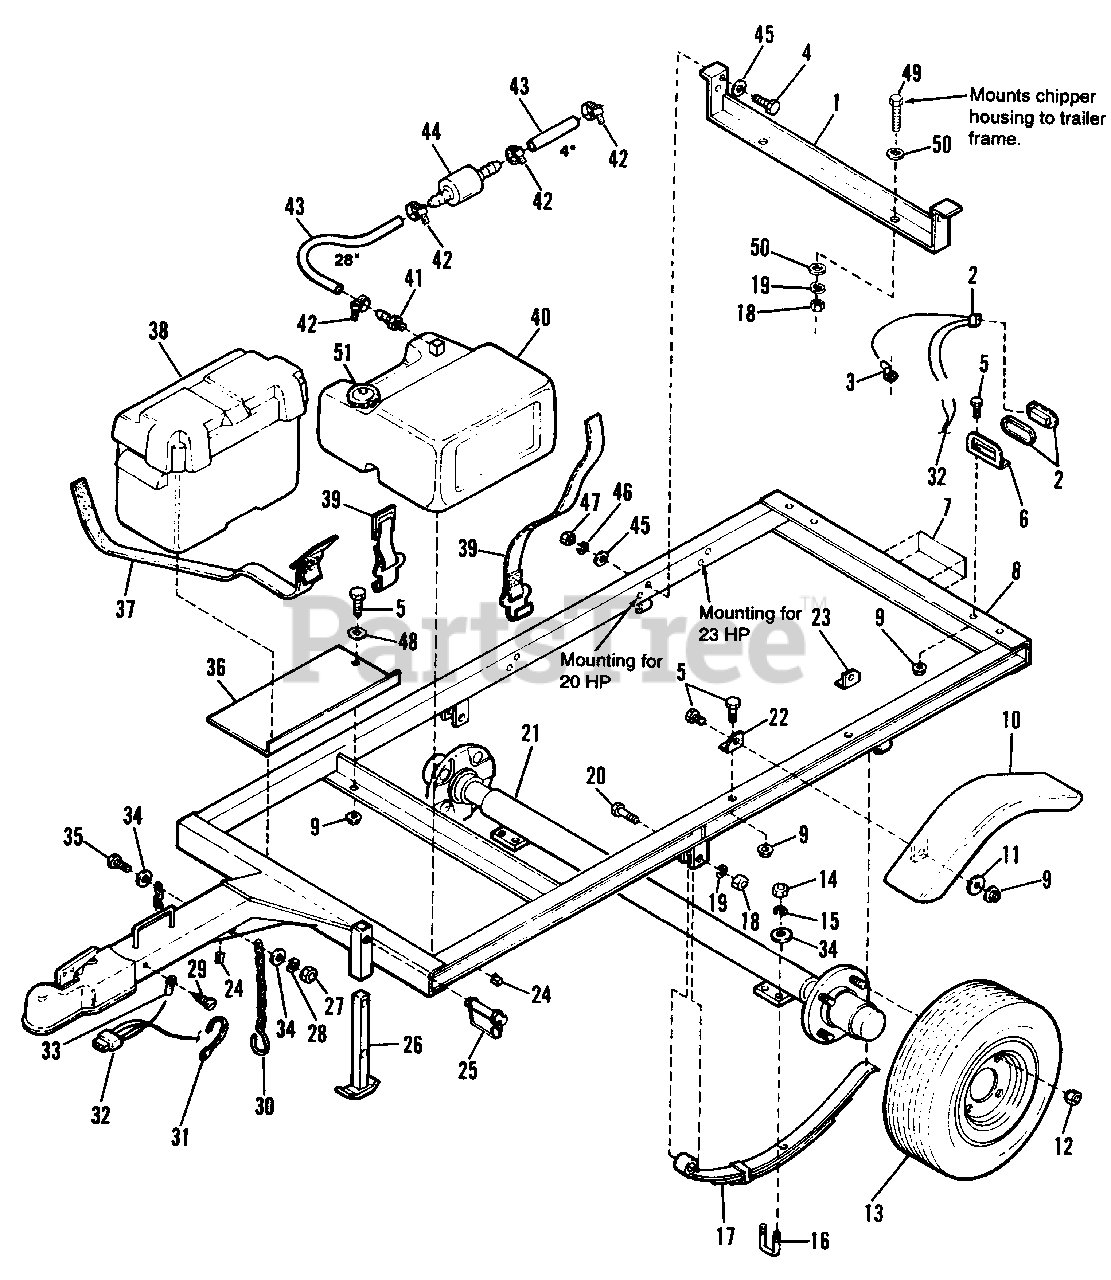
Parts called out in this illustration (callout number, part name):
1	BRACKET, Mounting, 20 HP
1	BRACKET, Mounting, 23 HP
2	TRUCK LIGHT
3	RING TONGUE, Vinyl
4	CAPSCREW, 7/16-14 x 1-1/4
5	CAPSCREW, Hex Hd., 5/16-18 x 3/4
6	BRACKET, Light Mounting
7	LOGO, Baker
8	TRAILER ASSEMBLY
9	NUT, Whiz Lock, 5/16-18
10	FENDER, Round
11	WASHER, Fender, 5/16 x 1-1/4 O.D.
13	WHEEL & TIRE ASSY., 5.70 x 8
14	NUT, 3/8 16
15	LOCKWASHER, 3/8
16	U-BOLT, 3/8-16
17	LEAF SPRING
18	NUT, Hex, 1/2-13
19	LOCKWASHER, 1/2
20	CAPSCREW, 1/2-13 x 3
21	AXLE ASSEMBLY
22	BRACKET, Fender Mounting, L.H.
23	BRACKET, Fender Mounting, R.H.
24	CLAMP, Cable
25	LOCK, Snap, 1/2 x 3-1/2
26	JACK ASSEMBLY
27	NUT, Hex, 3/8-16
28	LOCKWASHER, 3/8
29	SCREW, Sheet Metal
30	SAFETY CHAIN
31	TIE, Wore, 4"
32	HARNESS, Wiring, 117-1/2
33	TONGUE, Nylon Ring
34	WASHER, 3/8
35	CAPSCREW, 3/8-16 x 1-1/2
36	TRAY, Battery
38	CASE, Battery (Includes Ref. No. 37)
39	TIE DOWN, Gas Tank
40	TANK, Gas, 6 Gal. (Incl. Ref. No. 51)
41	FITTING, Male, Nylon, 1/4
42	CLAMP, Hose (Qty. 2 on 23 HP model)
43	FUEL LINE, 1/4 (4" & 28" Sections)
46	LOCKWASHER, 7/16-14
47	NUT, Hex, 7/16-14
48	WASHER, 5/16
49	CAPSCREW, Hex, 1/2-13 x 1-1/2
50	WASHER, Flat, 1/2
